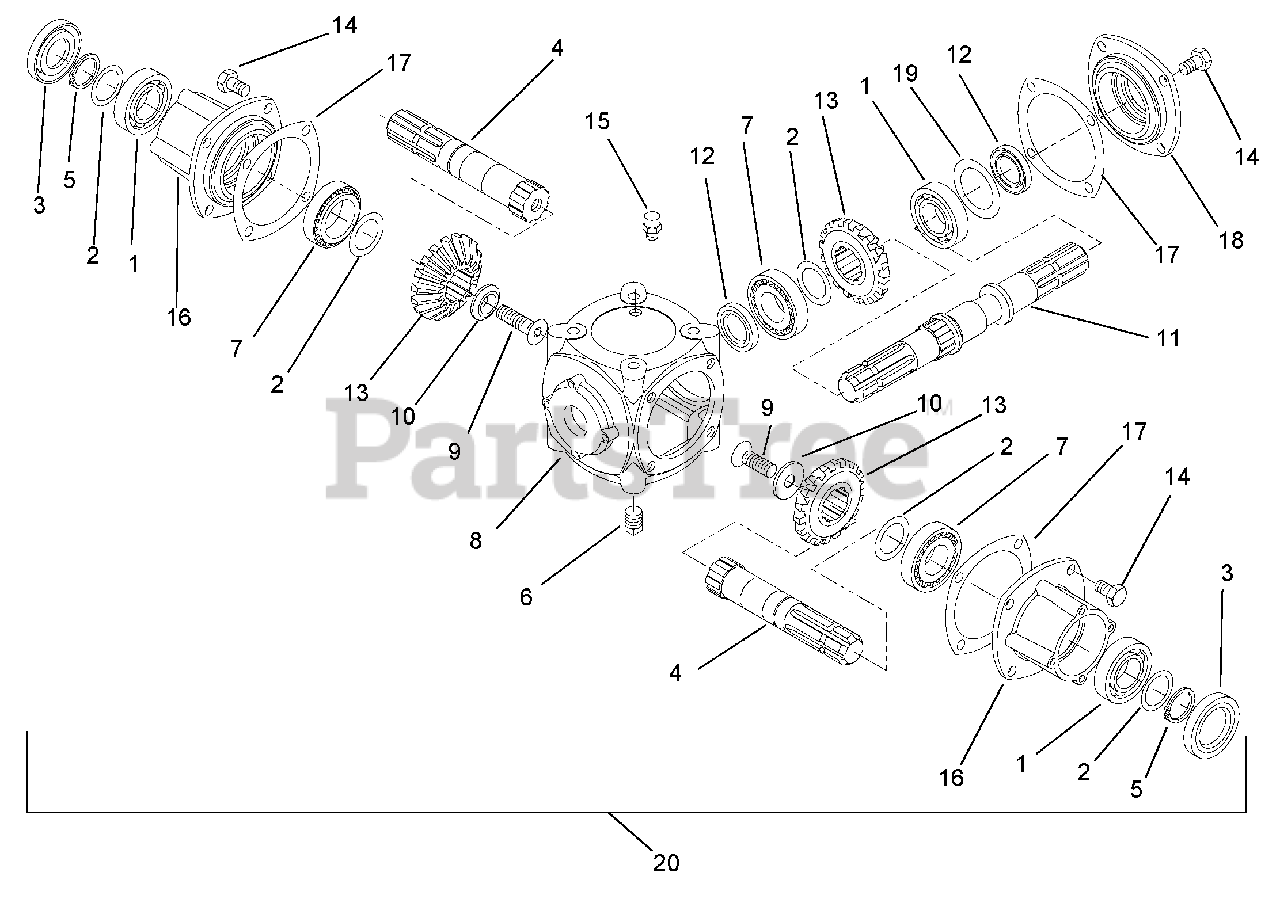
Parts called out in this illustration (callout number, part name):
2	Kit, Shim
3	Seal, Oil
5	Ring, Retaining
6	Plug, OIl
9	Bolt M12 x 40; 10.9
12	Seal, Oil
13	Gear Z.18 M.5
14	Seal, Oil
15	Plug, Valve Vent
16	Housing, Shaft
18	Cover, Gearbox Rear
19	Shim .3 mm
20	Gearbox Assembly, Center (Includes Items 1 – 19)
